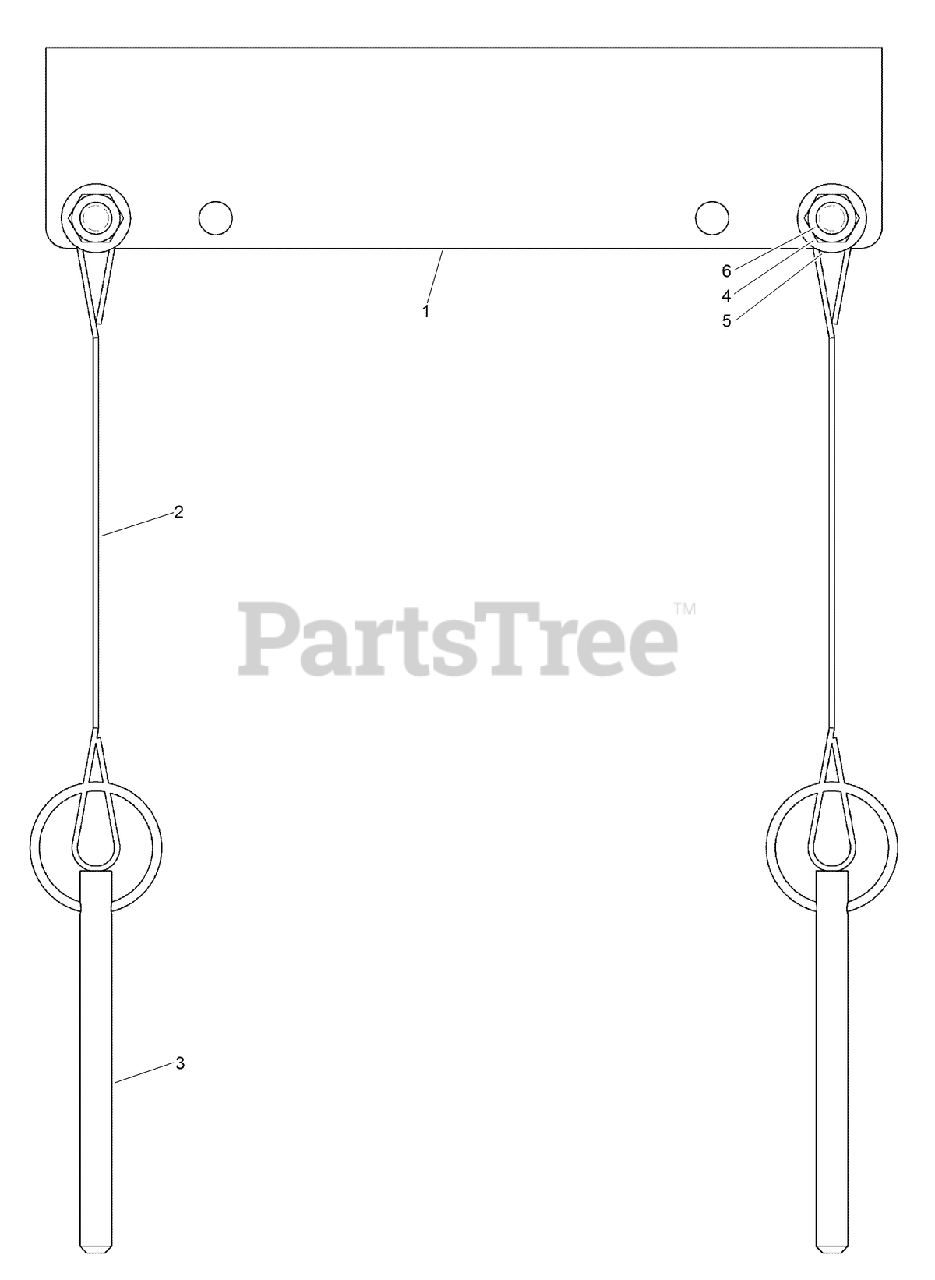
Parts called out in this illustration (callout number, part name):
1	PLATE - Tilt Cylinder Lockout
2	LANYARD-TETHER, PIN
3	PIN-RETAINING
4	SCREW-HH
5	WASHER-FLAT
6	NUT-HEX
